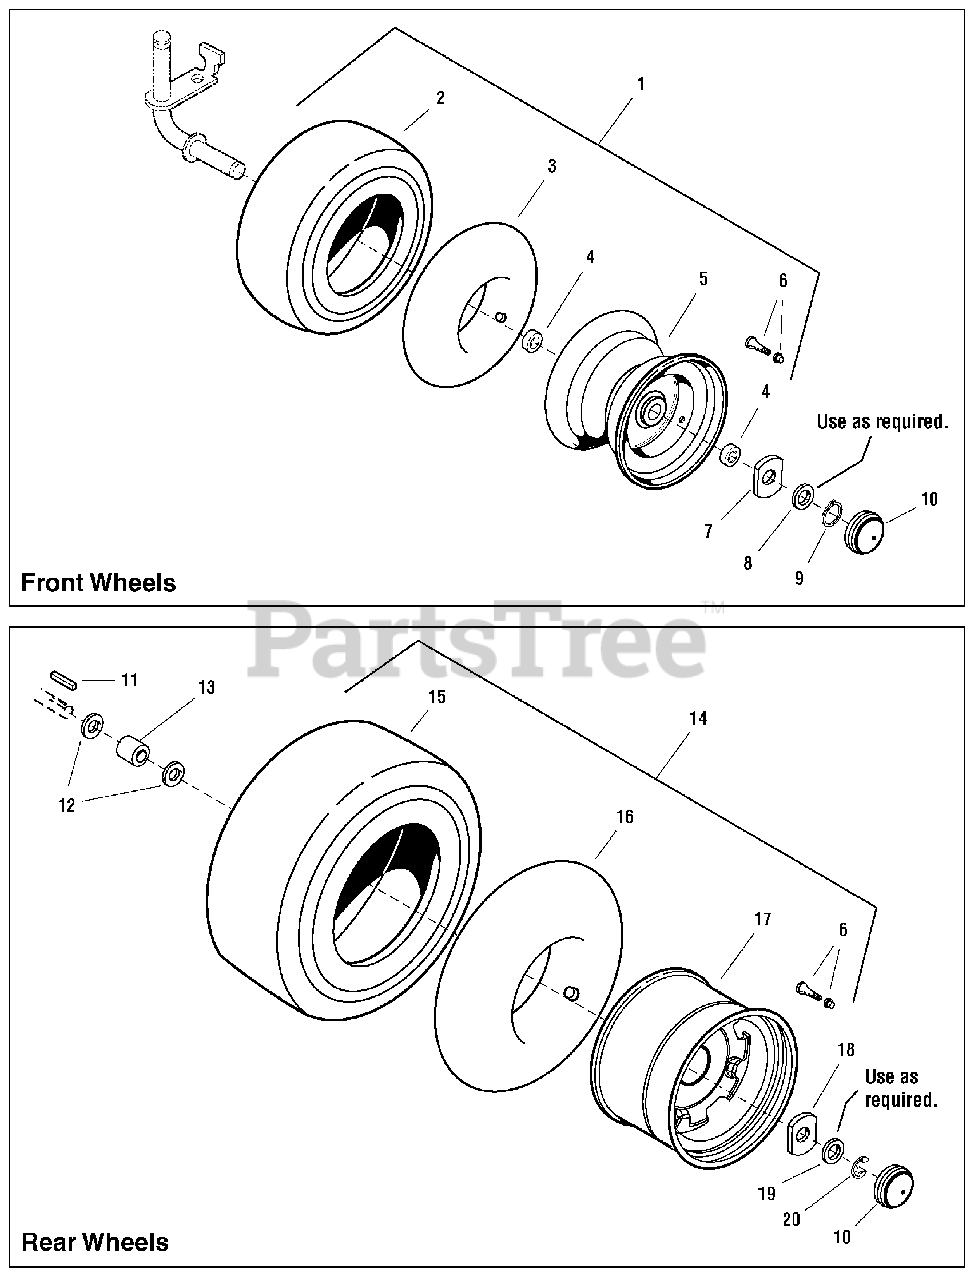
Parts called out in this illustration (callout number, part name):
1	WHEEL & TIRE ASSEMBLY, Front, (Includes Ref. Nos. 2, 3, 4, 5, & 6)
2	TIRE, 15 x 6, Super Turf
3	TUBE, Tire, Front, 4.10/3.50
4	BEARING, Ball
5	WHEEL, 4-1/2" x 6"
6	VALVE STEM & CAP ASSEMBLY
7	WASHER, Special
8	WASHER, 1
9	RING, Retaining, External #98
10	CAP, Hub, Gray
11	KEY, Parellel, 3/16 x 3/16 x 1-1/2
12	WASHER, 3/4
13	SPACER
14	WHEEL & TIRE ASSEMBLY, Rear, (Includes Ref. Nos. 6, 15, 16 & 17)
15	TIRE, 22 x 10, 10 Super Turf
16	TUBE, Tire, 20 x 8, Rear
17	WHEEL, 7 x 9.97 Dia. 3/4 ID, Hub
18	WASHER, Special
19	WASHER, 3/4 x 1-1/16 x 5/64
20	RING, "E" External
